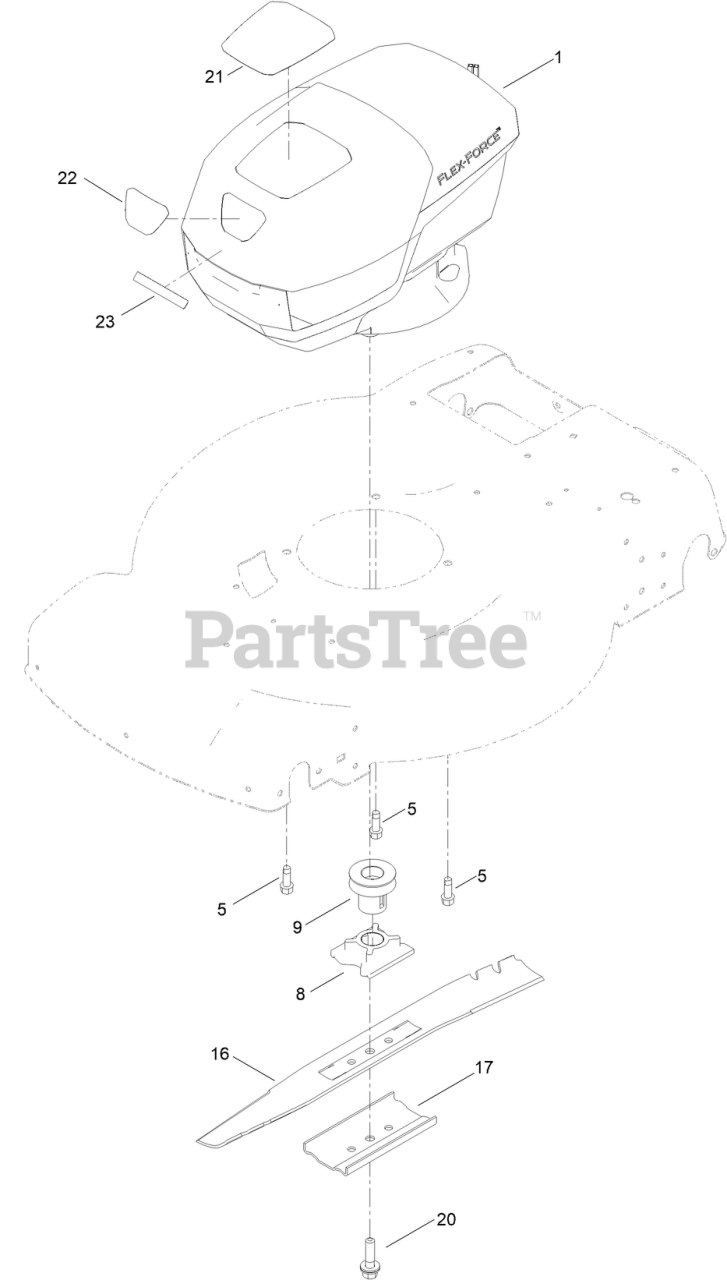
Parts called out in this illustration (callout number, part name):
1	MOTOR MODULE (60V)
5	SCREW-THD FORM, HWH
8	RETAINER-BLADE
9	PULLEY
16	BLADE [BLACK]
17	SUPPORT-BLADE
20	BOLT-BLADE
